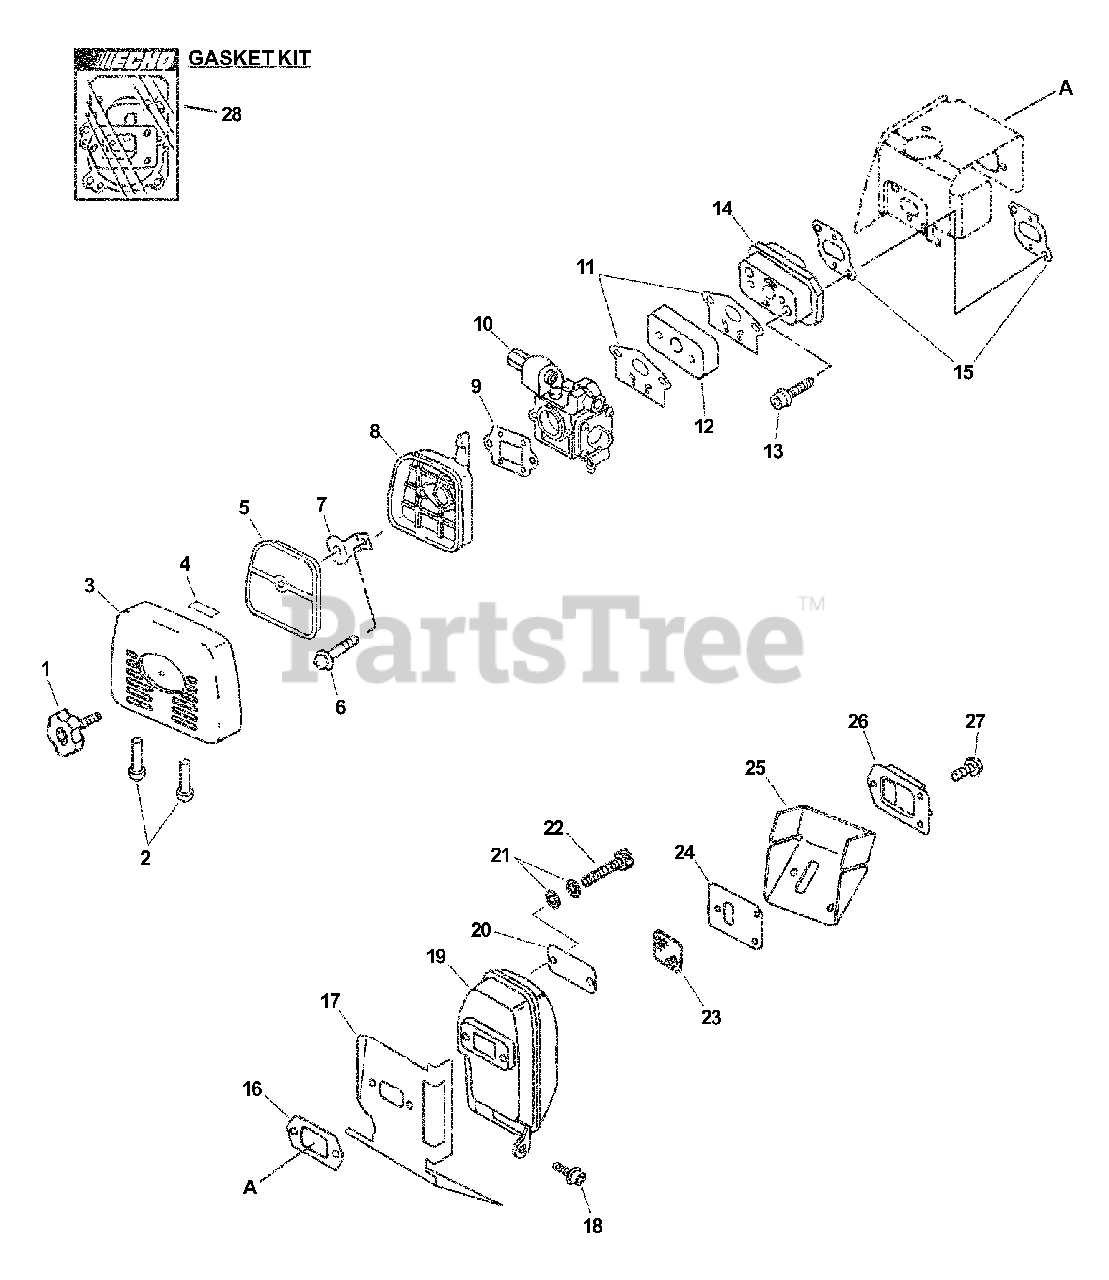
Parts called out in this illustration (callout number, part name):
1	THUMBSCREW
3	COVER, AIR FILTER
4	LABEL - CHOKE
5	FILTER, AIR - HEAVY DUTY
6	SCREW - 5X65
7	PLATE, PREVENT
8	CASE, AIR FILTER
10	CARBURETOR RB-K61A
11	GASKET, INTAKE
12	INSULATOR, INTAKE
13	SCREW - 5X25
14	INSULATOR, INTAKE
15	GASKET, INTAKE
16	GASKET, EXHAUST
17	SHIELD, EXHAUST
18	SCREW - 5X16
19	MUFFLER
21	WASHER - CONICAL
22	BOLT - 5X65
23	SCREEN, SPARK ARRESTOR
24	GASKET, EXHAUST
25	GASKET, EXHAUST
26	GUIDE, EXHAUST
27	SCREW - 4X12
28	GASKET KIT
